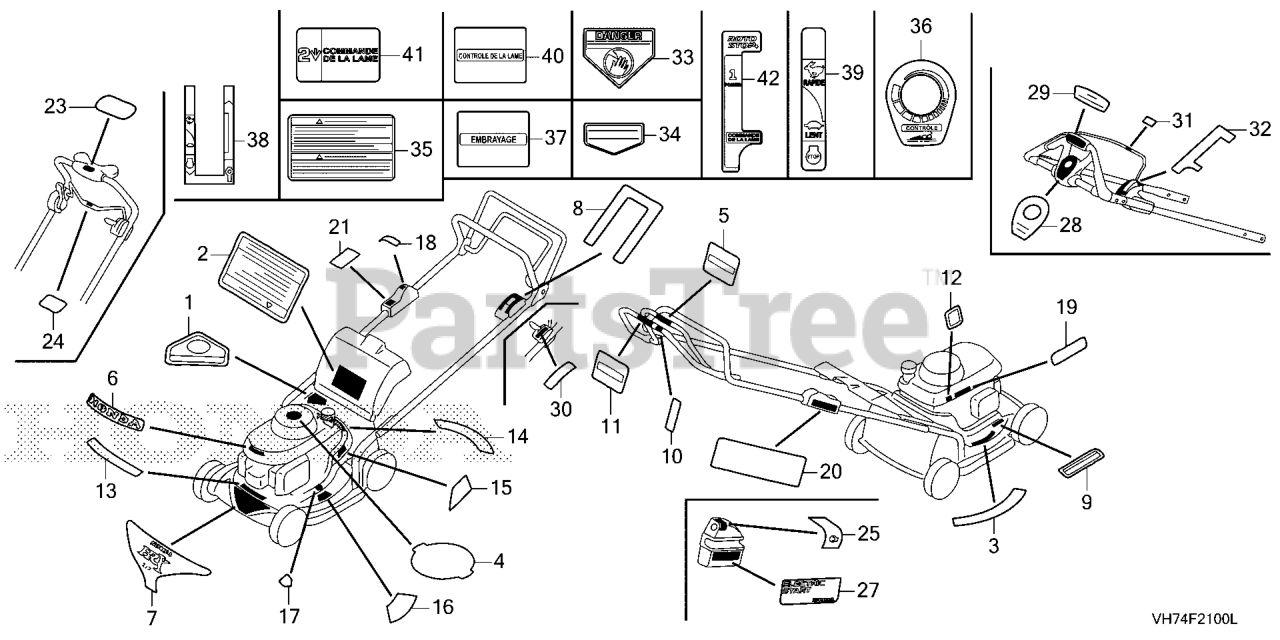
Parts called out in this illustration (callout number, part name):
1	LABEL C, HOUSING CAUTION
2	LABEL, WARNING (ENGLISH)
4	MARK, RECOIL COVER
7	MARK, HONDA
9	LABEL, HEAT WARNING
12	MARK, OIL CAUTION
13	MARK, SALES POINT (HRX)
14	MARK, CONTROL
15	MARK, CLIP DIRECTOR
25	MARK, ENGINE SWITCH
27	MARK, ELECTRIC STARTER
28	MARK, CONTROL OPERATION
29	MARK, CONTROL
31	MARK, BLADE CONTROL (ENGLISH)
